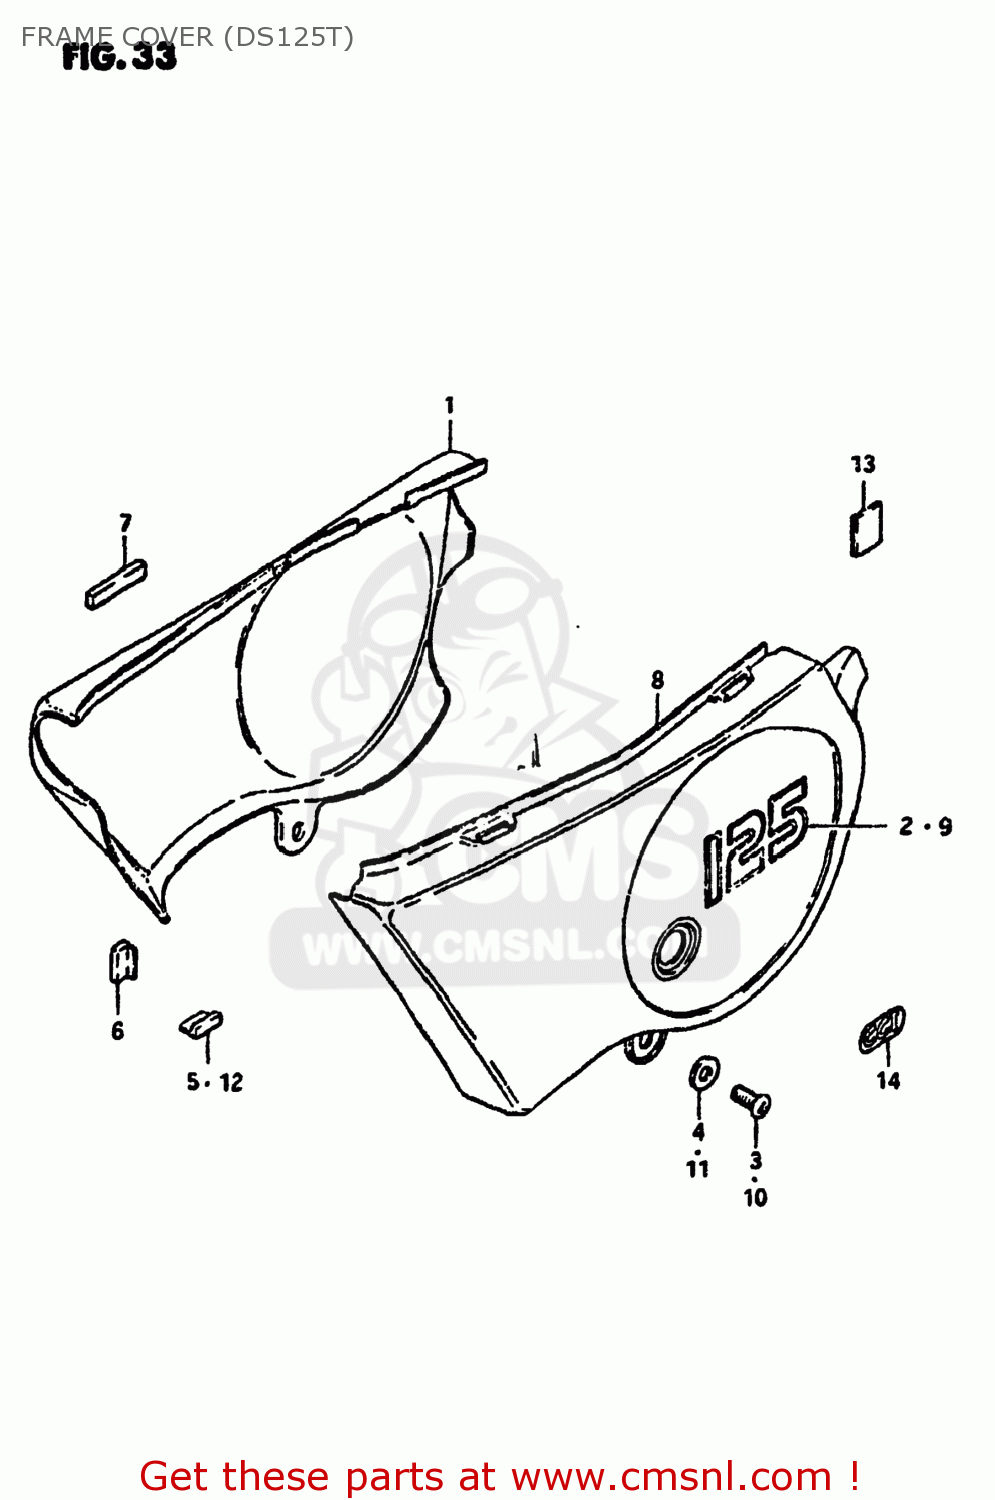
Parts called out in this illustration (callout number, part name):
1	COVER,FRAME,RIGHT
2	EMBLEM
3	SCREW 6X12
4	WASHER
5	CUSHION,FRAME COVER
6	CUSHION,FRAME COVER
7	CUSHION,FRAME COVER
8	COVER,FRAME,LEFT
9	EMBLEM,FRAME COVER
10	SCREW 6X12
11	WASHER
12	CUSHION,FRAME COVER
13	PROTECTOR(170X95X3.0)
14	EMBLEM,CCIS
